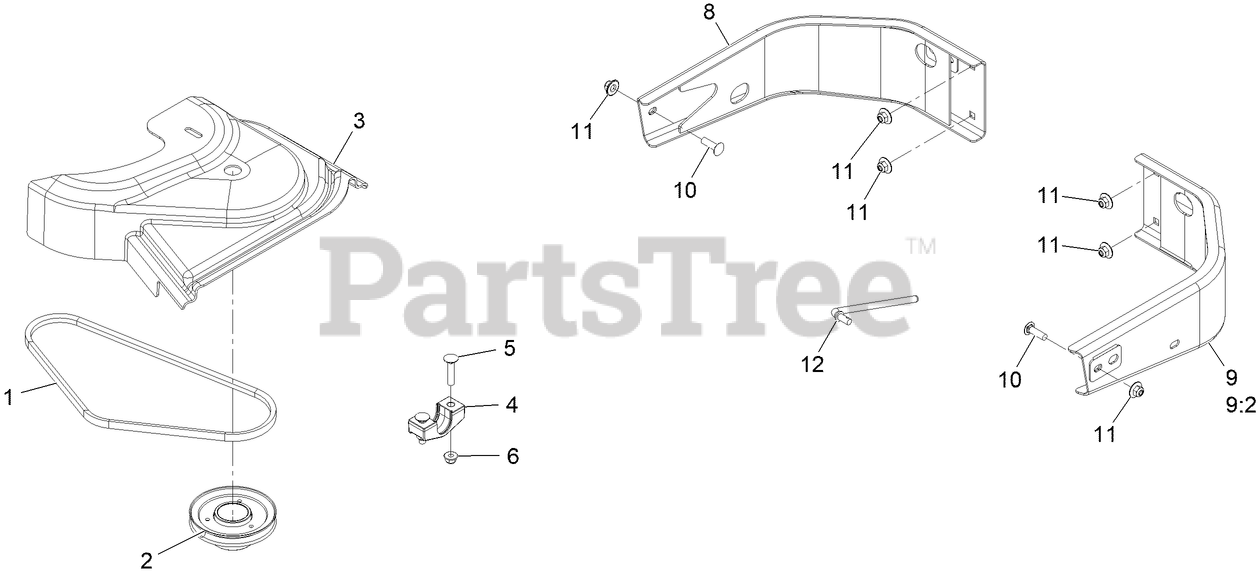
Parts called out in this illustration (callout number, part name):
2	SHEAVE,DRIVE LZUV 606
3	COVER,BELT UV 60
4	SUPPORT-BEARING CROSS SHAFT
5	SCREW-CARR
6	NUT-HF, NI
8	BUMPER-RH
9	LH BUMPER ASM
9:2	DECAL-WARNING
10	Bolt-Carriage 3/8-16 X 1 1/4
11	Nut-Nyloc 3/8-16 Flg
12	LINK-HANDLE
